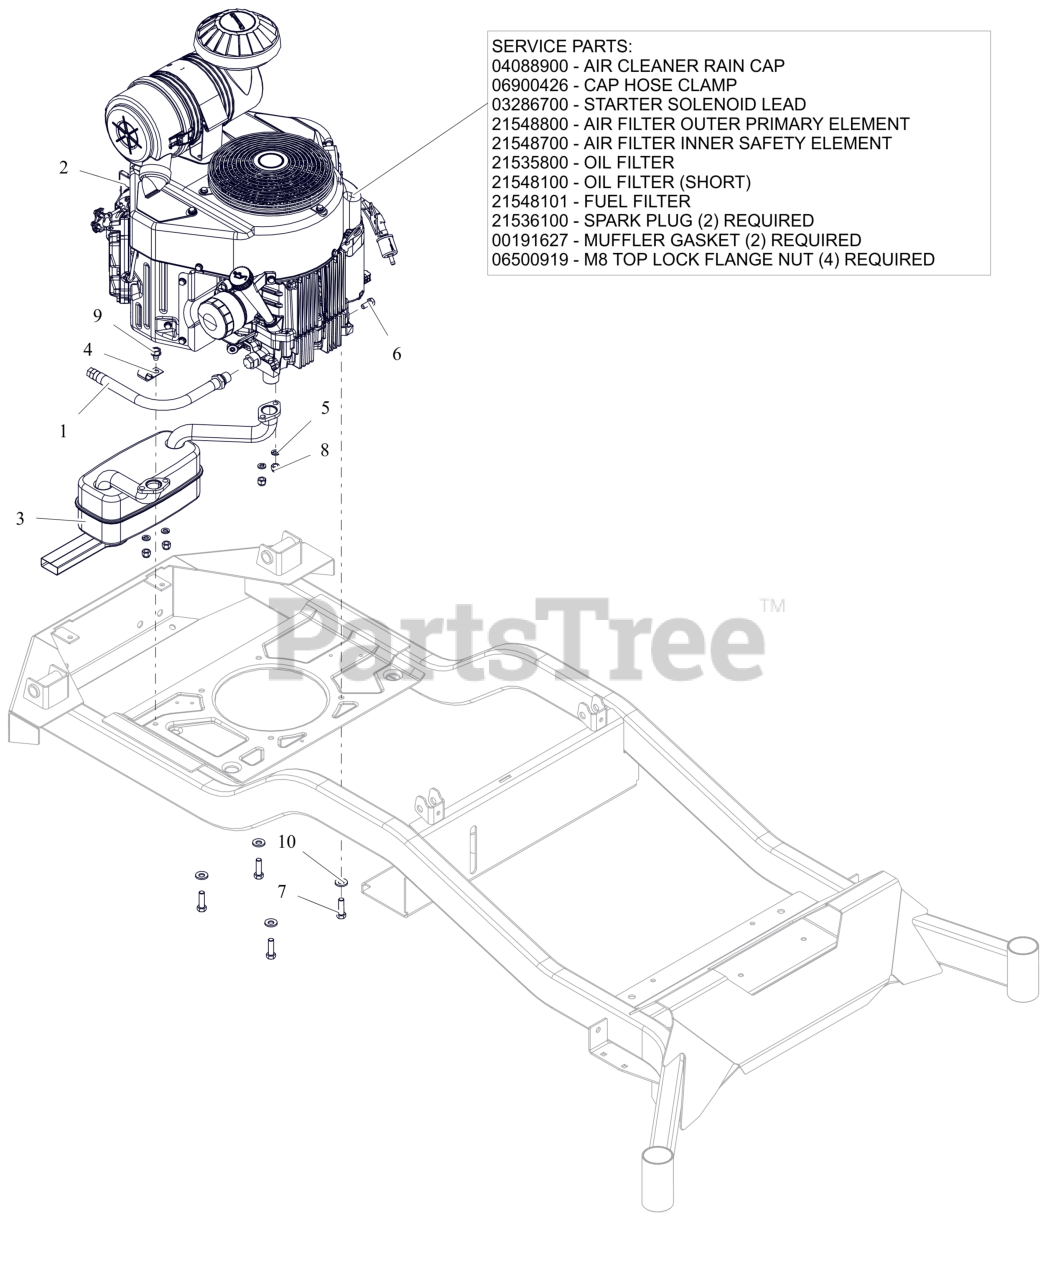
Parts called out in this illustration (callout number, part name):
1	HOSE, OIL DRAIN
2	ENGINE, KAWASAKI - FX730
2	CAP, KAW 11065-7025
2	CLAMP, HOSE #36 SS 1.813-2.75
2	LEAD - STARTER SOLENOID
2	FILTER, OUTER
2	FILTER, INNER - KAW
2	FILTER,OIL - KAW
2	OIL FILTER, KAWASAKI FR
2	FUEL FILTER-KAWASAKI FR
2	PLUG, SPARK
2	GASKET, MUFFLER S/O
2	NUT-LK-TOP-FLG M8 ZCC
3	MUFFLER, KAWASAKI
4	J-CLAMP
5	WSHR,LK-REG .312X.078 ZCC
6	BLT, HEX M8-1.25X20 G8.8 ZCC
7	BLT, HEX .38-16X1.25 G5 ZCC NT
8	NUT, LK-CTR-JAM M8-1.25 GR8.8 ZC120
9	SCR,TAP .375-16X.50 HWH TR ZCC
10	WASHER, 3/8" SPRING DISC
